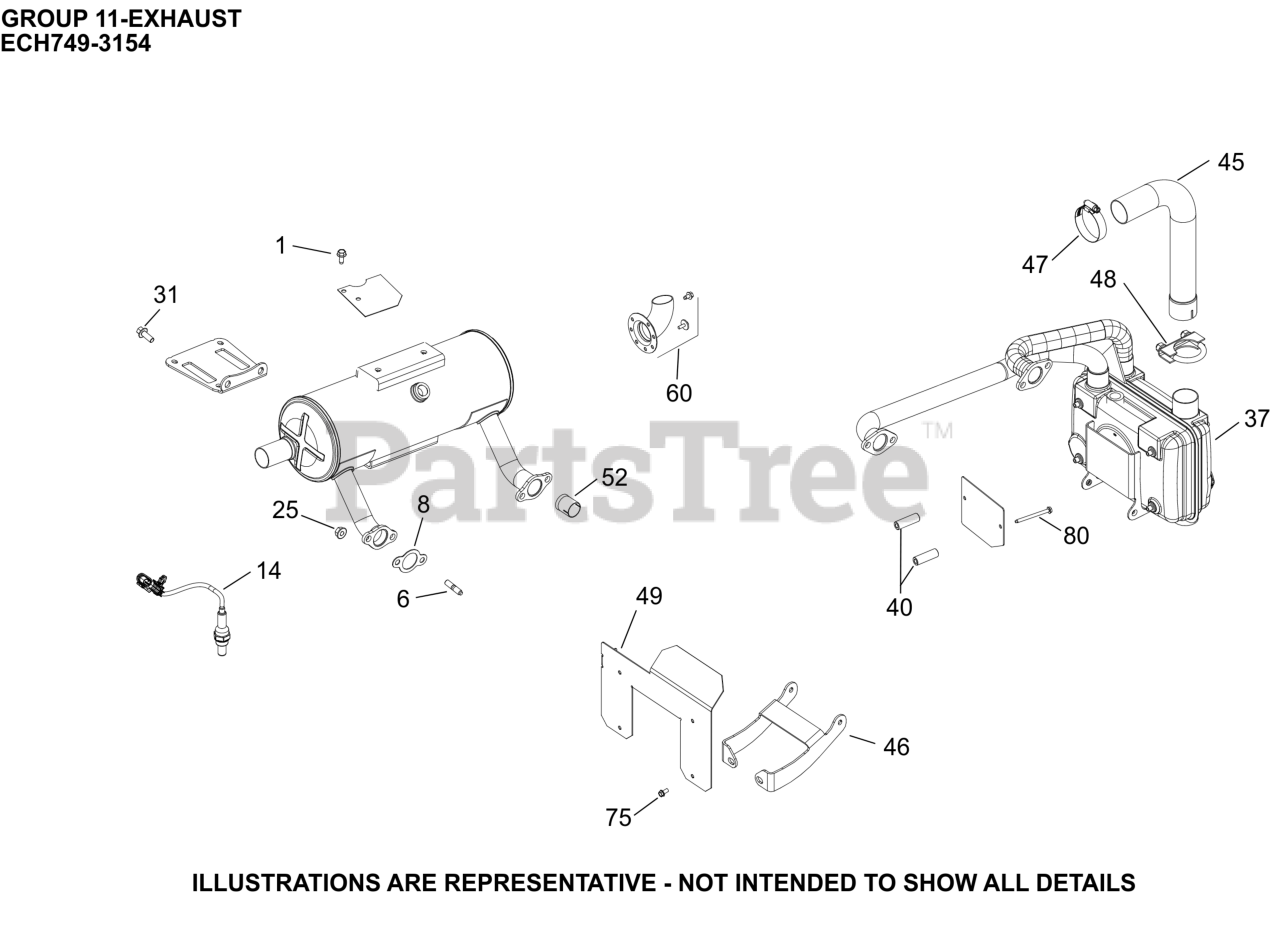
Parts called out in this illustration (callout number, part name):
1	SCREW, THREAD FORMING
6	STUD, METRIC EXHAUST
8	GASKET, EXHAUST MANIFOLD
14	SENSOR, OXYGEN (M18 x 1.5 THREADS)
25	NUT, FLG M8X1.25
31	SCREW, FLG M8X1.25X20
37	MUFFLER, ASSEMBLY
40	SPACER, ECU GUARD
45	TUBE, CONNECTOR
46	BRACKET, MUFFLER
47	CLAMP, HOSE
48	CLAMP, MUFFLER
49	SHIELD,HEAT(STRTR SIDE CH26/745)
52	LINER, EXHAUST PORT
60	KIT, DEFLECTOR-PIPE
75	SCREW, SERRATED
80	SCREW, HEX WASHER HEAD
